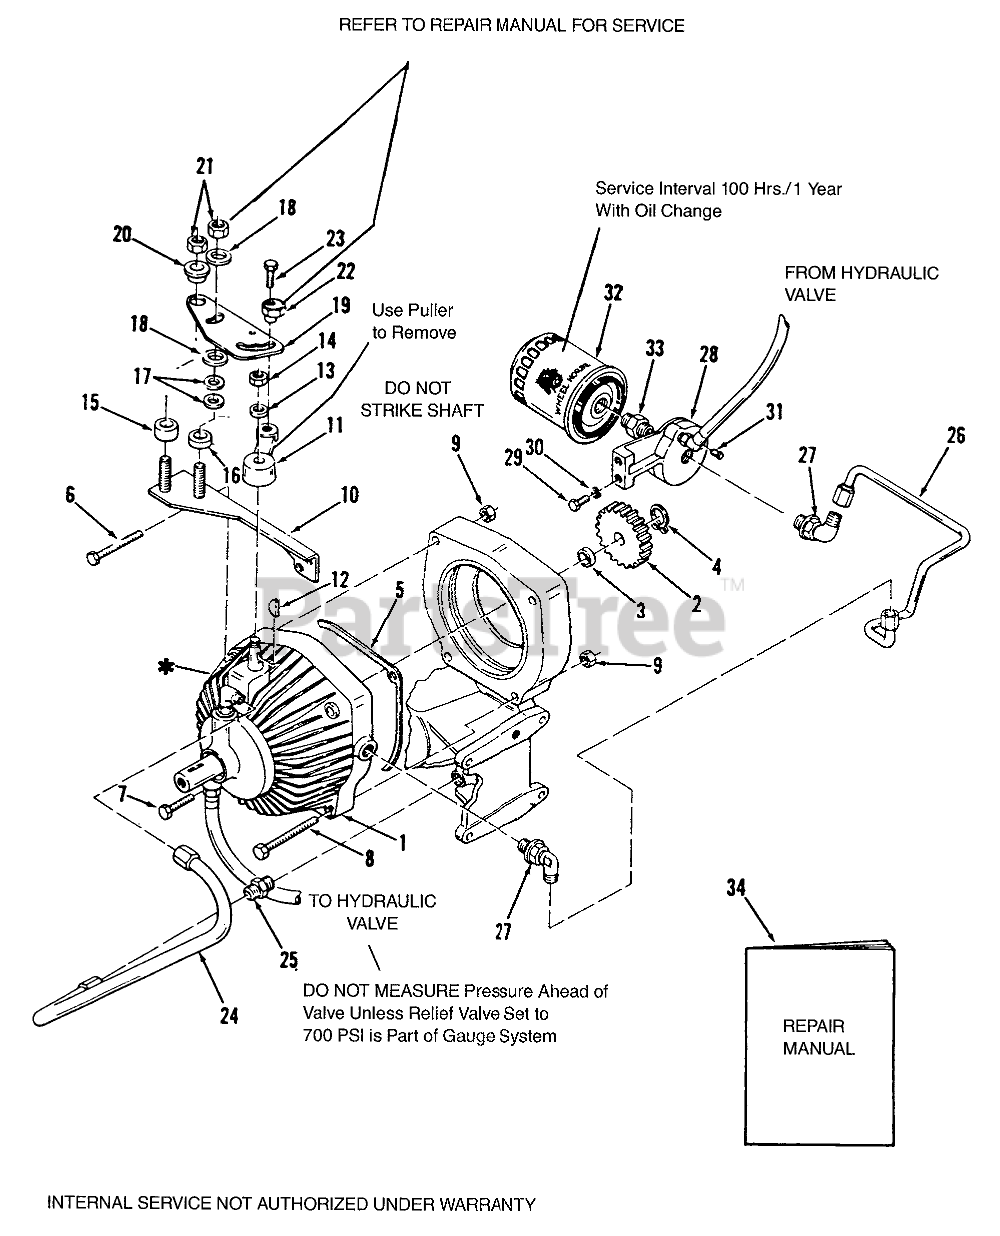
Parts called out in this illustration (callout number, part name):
1	Pump & Motor
2	GEAR 22T DRIVE
3	SPACER GEAR
4	SNAP RING- 5/8 EXT
5	GASKET
6	Hex Bolt
7	Bolt
8	Bolt 3/8-16 x 6 1/2
9	NUT
10	ASSY-PLATE B
11	ARM-SPEED CONTROLB
12	Key #5 Woodruff
13	Washer
14	Nut
15	SPACER-PIVOT
16	SPACER-FRICTION
17	WASHER-SPRING DISC
18	FRICTION WASHER
19	CAM-SPEED CONTROL (NS)
20	CAM-SPACER
23	Bolt
24	ASSY-TUBE SUCTION
25	FITTING-TUBE
26	ASM-TUBE FILTER OUTL
27	ELBOW
28	BASE-FILTER
29	Bolt
30	Lockwasher
31	PLUG 1/4 PIPE ALLEN
32	Filter-Oil
33	FITTING
34	Repair Manual
